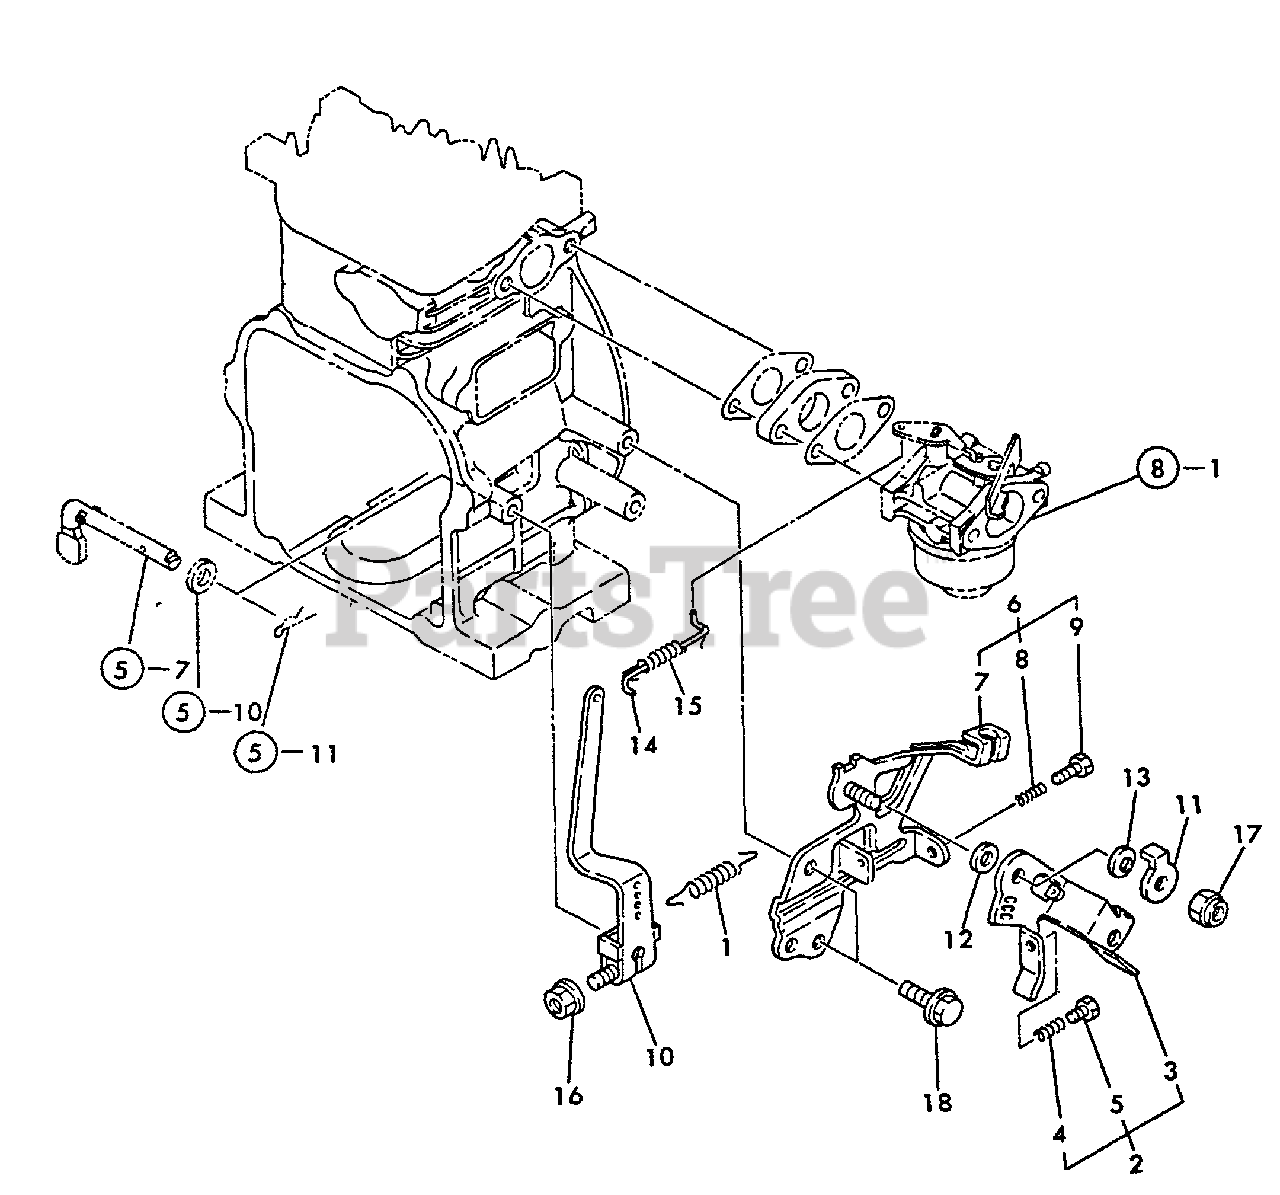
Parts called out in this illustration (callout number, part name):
1	SPRING, REGULATOR
2	REGULATOR HANDLE ASSY
3	HANDLE, REGULATOR
4	SPRING, IDLE
5	BOLT - 4X20
6	REGULATOR BASE ASSY
7	BASE, REGULATOR
8	SPRING, IDLE
9	BOLT - 4X25
10	LEVER, COVER
11	WASHER
12	WASHER - NYLON
13	SPRING, PLATE
14	LINK, THROTTLE
15	SPRING, THROTTLE
16	NUT - 6 -- FLANGE
17	LOCKNUT
18	BOLT - 6X8 -- PLATED
